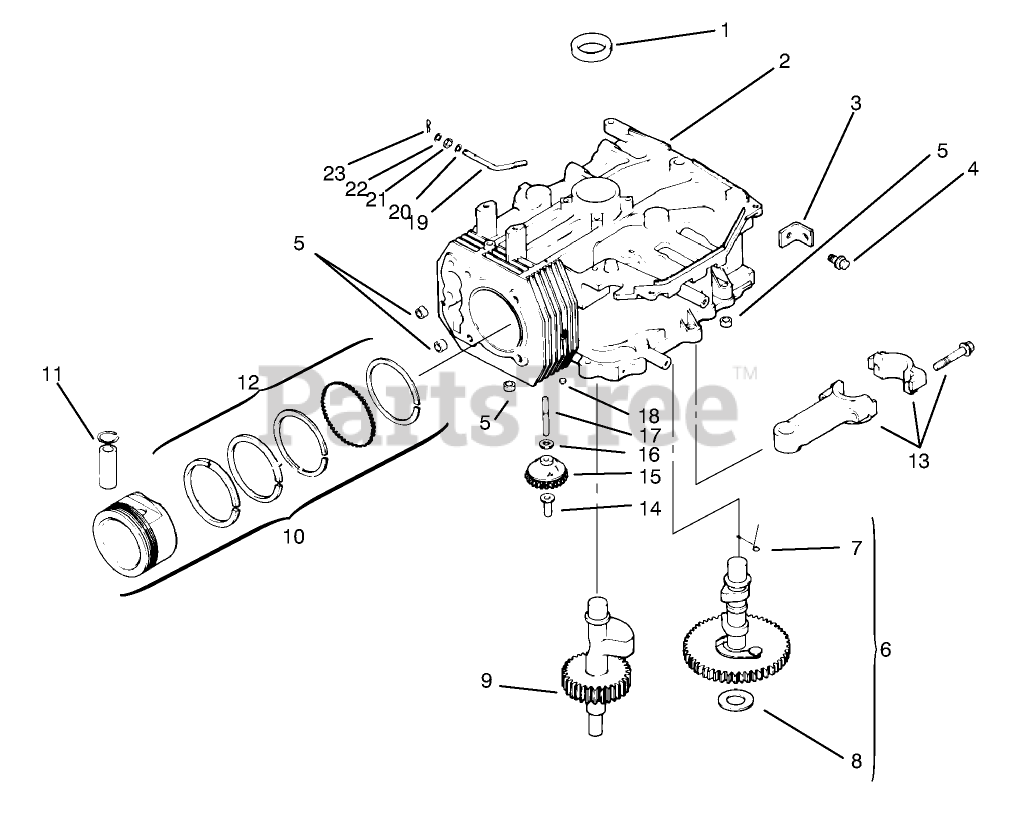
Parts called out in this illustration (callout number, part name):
1	Seal-Crankshaft (Only On: 72042, 72043, 72062, 72063)
2	Block-Short
3	Strap-Lifting (Only On: 72042,72043,72062,72063)
4	Screw M8x1.25x22 (Only On: 72042, 72043, 72062, 72063)
5	Pin-Dowel
6	Kit-Camshaft INC 7-8 (Only On: 72042, 72063, 72062, 72043)
7	Spring-Actuating (Only On: 72042,72043,72062,72063)
8	Shim-Camshaft
9	Shaft-Balance
10	Piston ASM STD Incl 11-2
10	Piston ASM .25 Incl 11-2
10	Piston ASM .50 Incl 11-2
11	Retainer-Piston Pin (Only On: 72042, 72043,72062,72063)
12	Ring Set STD
12	Ring Set .25
12	Ring Set .50
13	Rod Connecting STD
13	Rod Connecting .25
14	Pin-Governor
15	Gear-Governor ASM (Only On: 72042, 72063, 72062, 72043)
17	Shaft-Govenor Gear
19	Kit-Governor Cross
20	Washer, plain 6 mm
21	Seal
22	Washer
23	Clip-Hitch Pin
